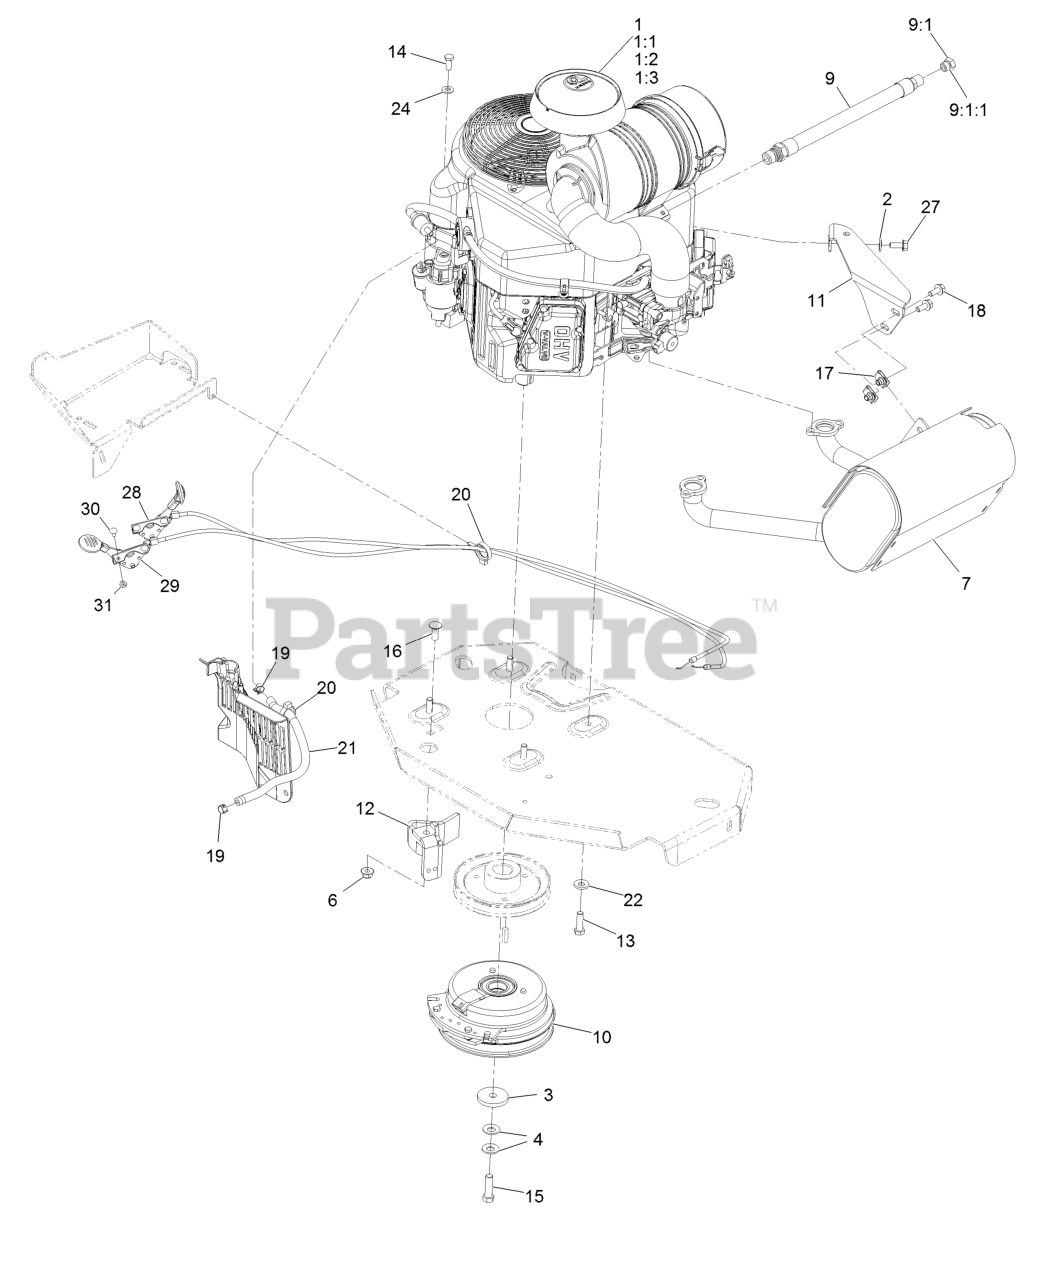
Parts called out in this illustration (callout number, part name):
1:1	Kawasaki 49065-7007 Engine Oil Filter
1:2	Kawasaki 11013-7044 Engine Air Filter
1:3	Kawasaki 11013-7045 Safety Filter
2	Washer-Spring Disc 5/16
3	Washer-Clutch
4	Washer-Spring Disc 7/16
6	Nut-Nyloc 3/8-16 Flg
7	Muffler
9	Asm-Hose Oil Drain W/Plug
9:1	Plug-W/O-Ring
9:1:1	O-Ring
10	Clutch Kit
11	Bracket-Muffler
12	Clutch-Anchor
13	Screw-HH 3/8-16 X 1 1/4
14	Screw-HH M8-1.25 X 20Mm
15	Screw-HH 7/16-20 X 1 1/2 W/Loctite
16	Bolt-Carriage 3/8-16 X 1
18	Screw-HH Flg 5/16-18 X 3/4
19	Clamp-Hose
20	Clamp-Hose
21	Hose-Fuel Line 15"
22	Washer-Spring Disc 3/8
27	Screw-HH M8-1.25 X 20Mm
28	ASM, Choke Cable
29	ASM,Throttle Cable
30	Bolt-Carriage #10-24 X 1/2
31	Nut-Nyloc #10-24
